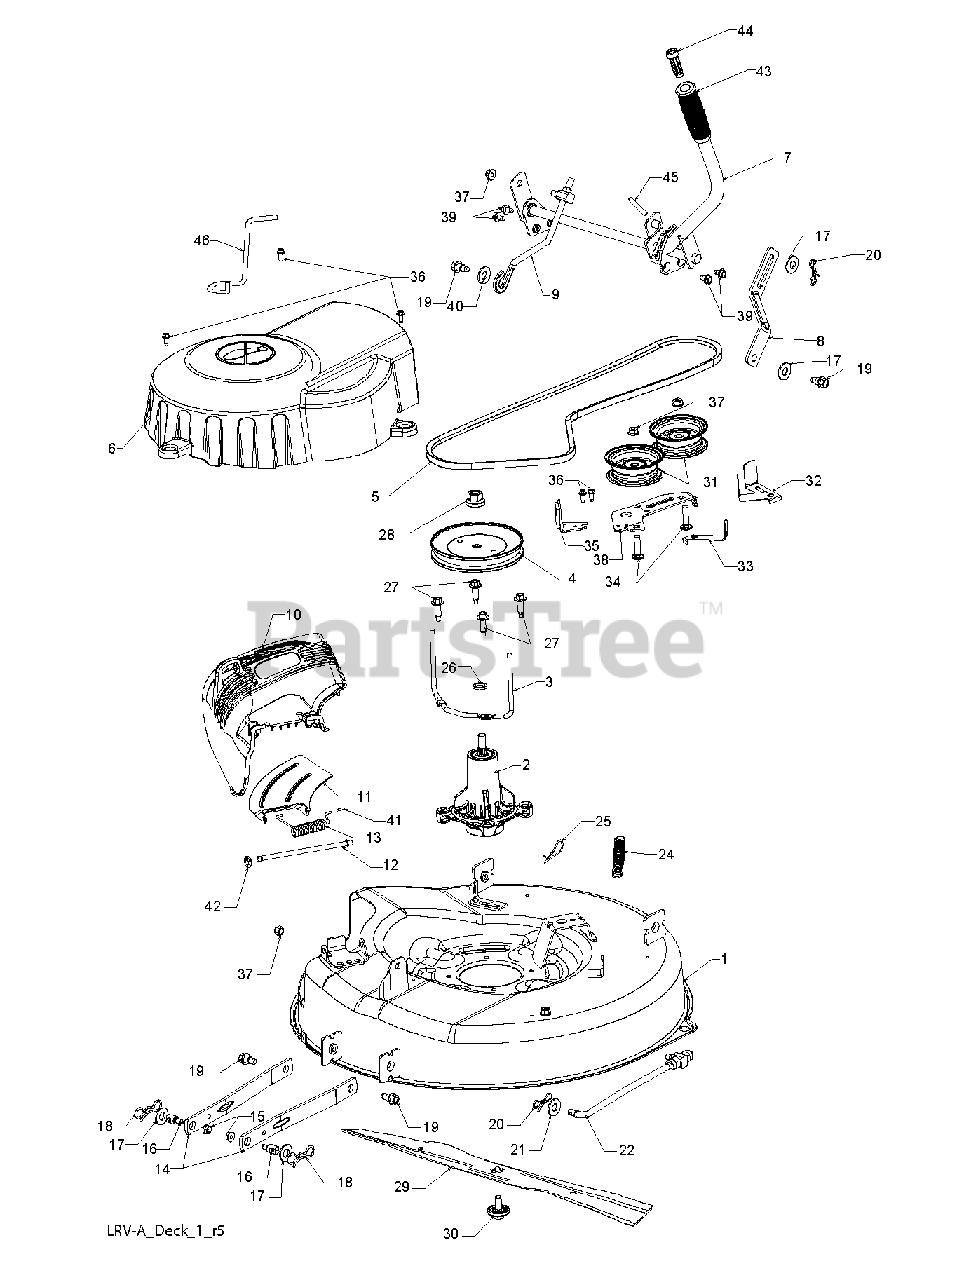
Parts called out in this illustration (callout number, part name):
1	DECK, 26"
2	MANDREL.ASM.SUB-NON.GR
3	KEEPER.BELT.MANDREL.PULLEY
4	PULLEY.MANDREL
6	COVER, MANDREL
7	LIFT.ASM.DECK.LRV
8	LINK, DECK LIFT
9	LINK.ASM.LIFT.ADJUSTABLE
11	SUPPORT, DEFLECTOR
12	ROD.HINGE
13	SPRING.TORSION.DEFLECT
14	ARMS.SUSP.MOWER.REAR.SRD
15	NUT LOCK HEX FLANGE 5/16-18
16	STUD.FASTNER.W/ANTI-ROTATE
17	WASHER.CLEAR.ZINC
18	PIN.COTTER.7/16.BOW TI.
19	BOLT.SHOULDER
20	PIN.COTTER.5/16.BOW TI
22	LINK.ASM.TOP.DECK.LRV
24	SPRING.EXTENSION.DECK.LRV
26	WASHER.SPACER.MANDREL
27	SCREW, WASHER HEAD
28	NUT.FLANGE.LOCK.TOP
29	BLADE.26"
30	BOLT.WASHER.ASM.7/16-2
31	PULLEY.IDLER.48"PRIMARY
32	GUARD, BELT
33	KEEPER BELT
34	BOLT.3/8-16X1.50
35	ARM BRAKE MOWER RH
36	SCREW.1/4-20X5/8
37	NUT LOCK FLG 3/8-16 UNC
38	ARM, IDLER
39	SCREW LT
41	CAP-SLEEVE LT
42	NUT PUSH M
43	GRIP HANDLE
44	PLUNGER.ASM.LRV
45	PIN GROOVE.
46	KEEPER.BELT
